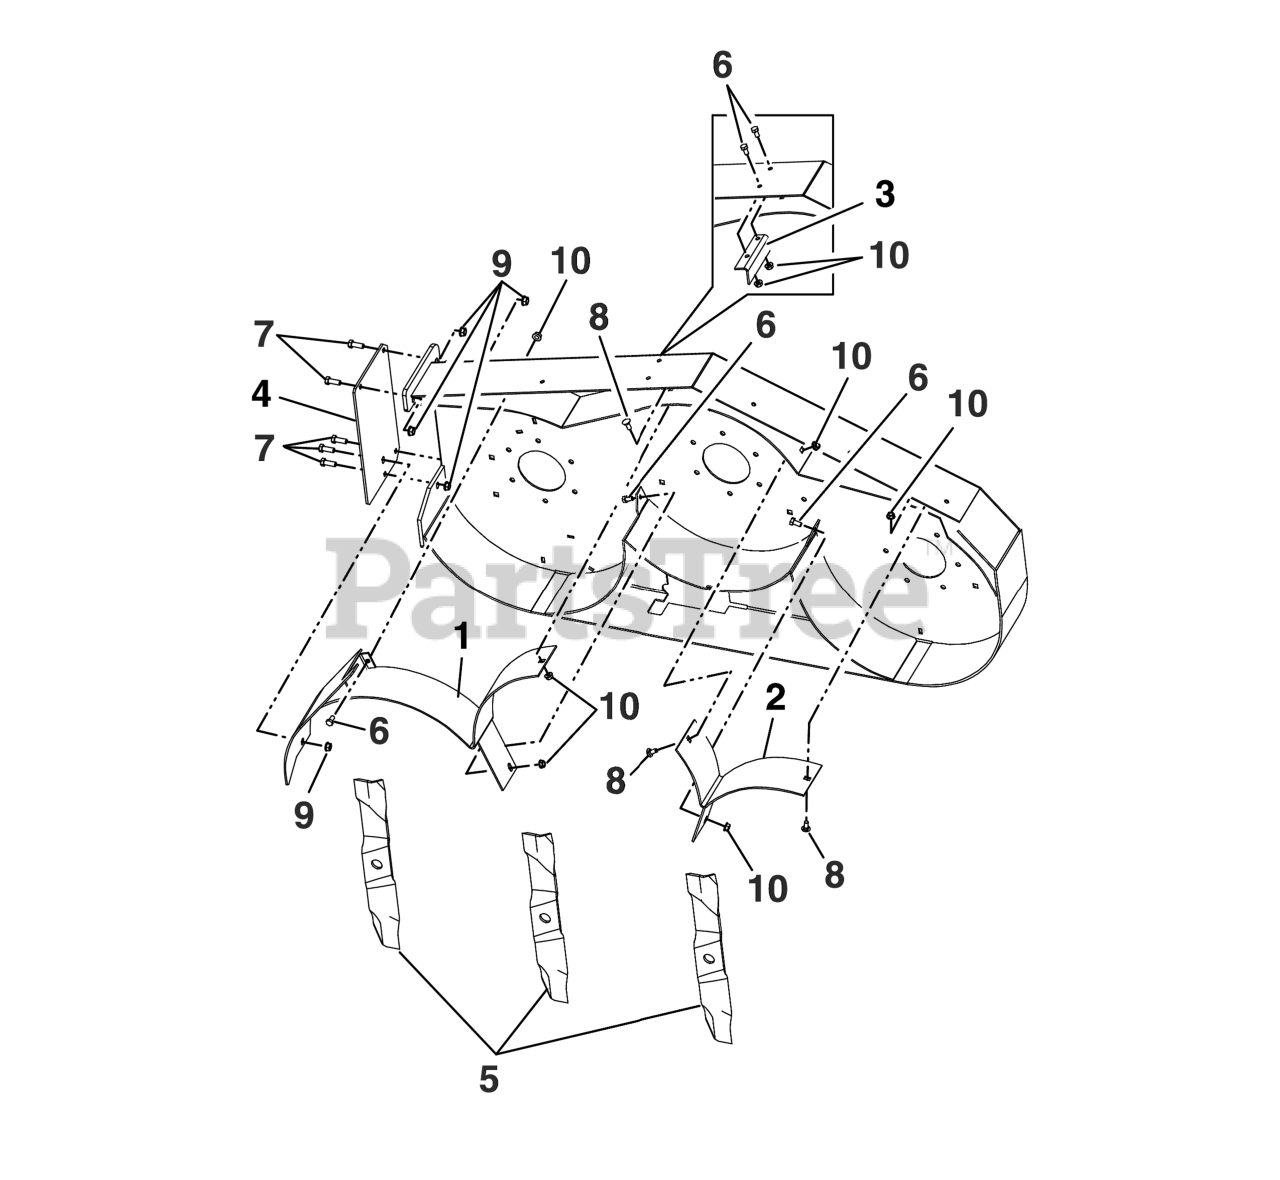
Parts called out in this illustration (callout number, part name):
1	WLD,BAFFLE MULCH RH 52
2	WLD,BAFFLE MULCH LH 52
3	BAFFLE,ZEE MULCH 52
4	COVER-MULCH PLATE
6	SCREW-HH
7	SCREW-HH
8	BOLT-CARR
9	NUT-HHF, WHIZ
